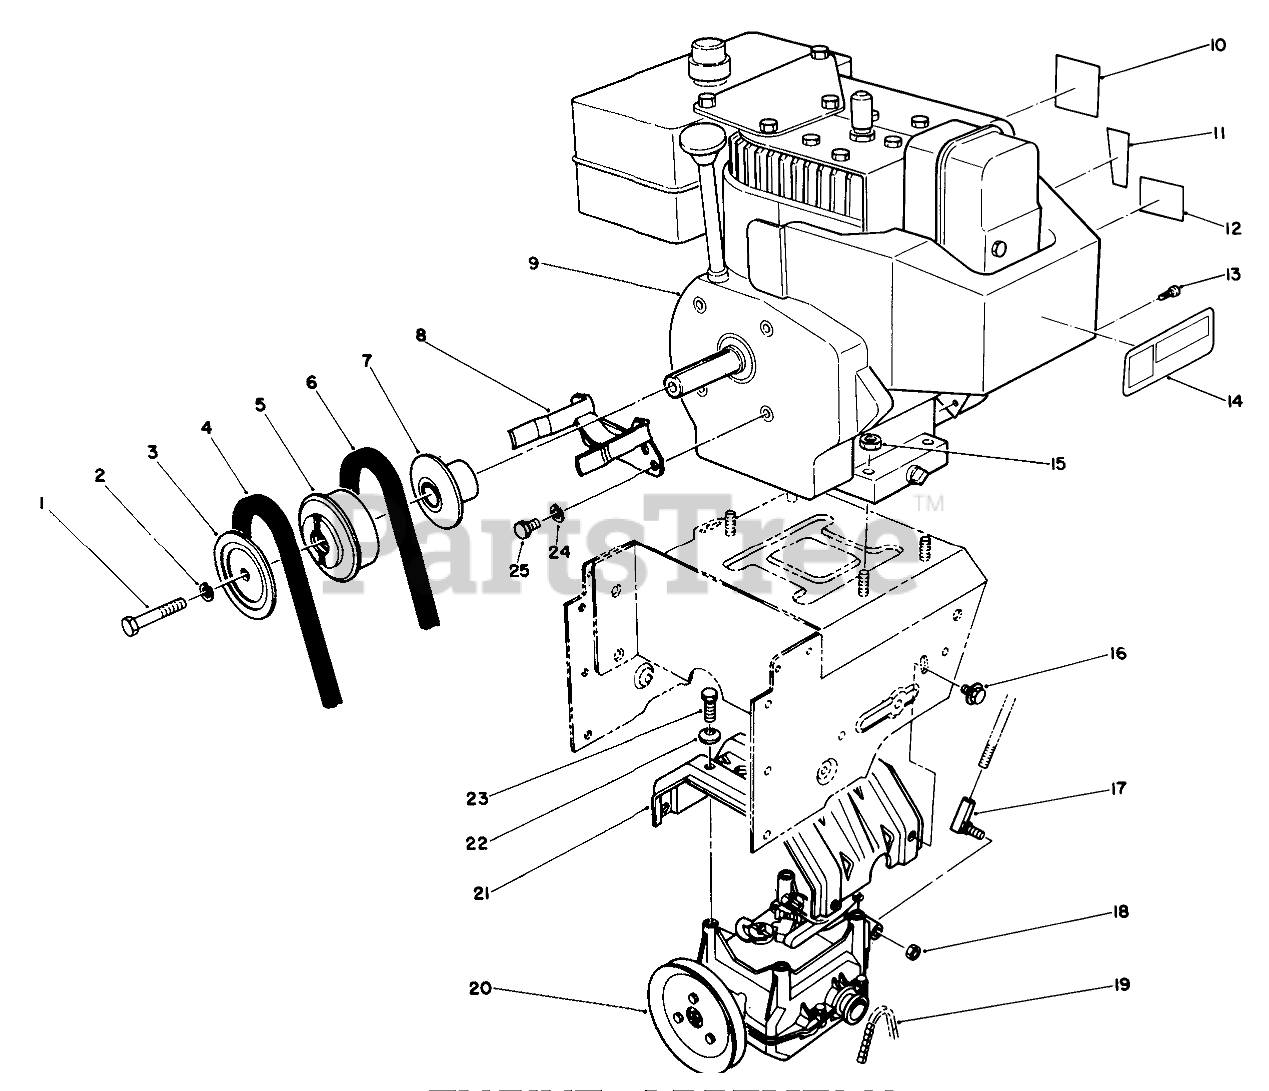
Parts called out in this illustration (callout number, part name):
1	SCREW-HH
2	WASHER-LOCK
3	SHEAVE-HALF, IMPELLER
4	V-BELT
5	PULLEY-ENGINE, CENTER
6	V-BELT-TRACTION
7	SHEAVE-HALF, TRACTION
8	Guide-Belt
10	DECAL-PRIMER
11	DECAL-THROTTLE
12	DECAL-CHOKE
13	SCREW-HWH
14	Decal-Hot
15	NUT-HF
16	SCREW-HHF
17	JOINT-BALL
18	NUT-LOCK, NI
19	CHAIN
20	TRACTION GEARCASE ASM
21	Frame-Transmission
22	WASHER-SPRING
23	SCREW-HWHTF
24	WASHER-LOCK
25	SCREW-HH
